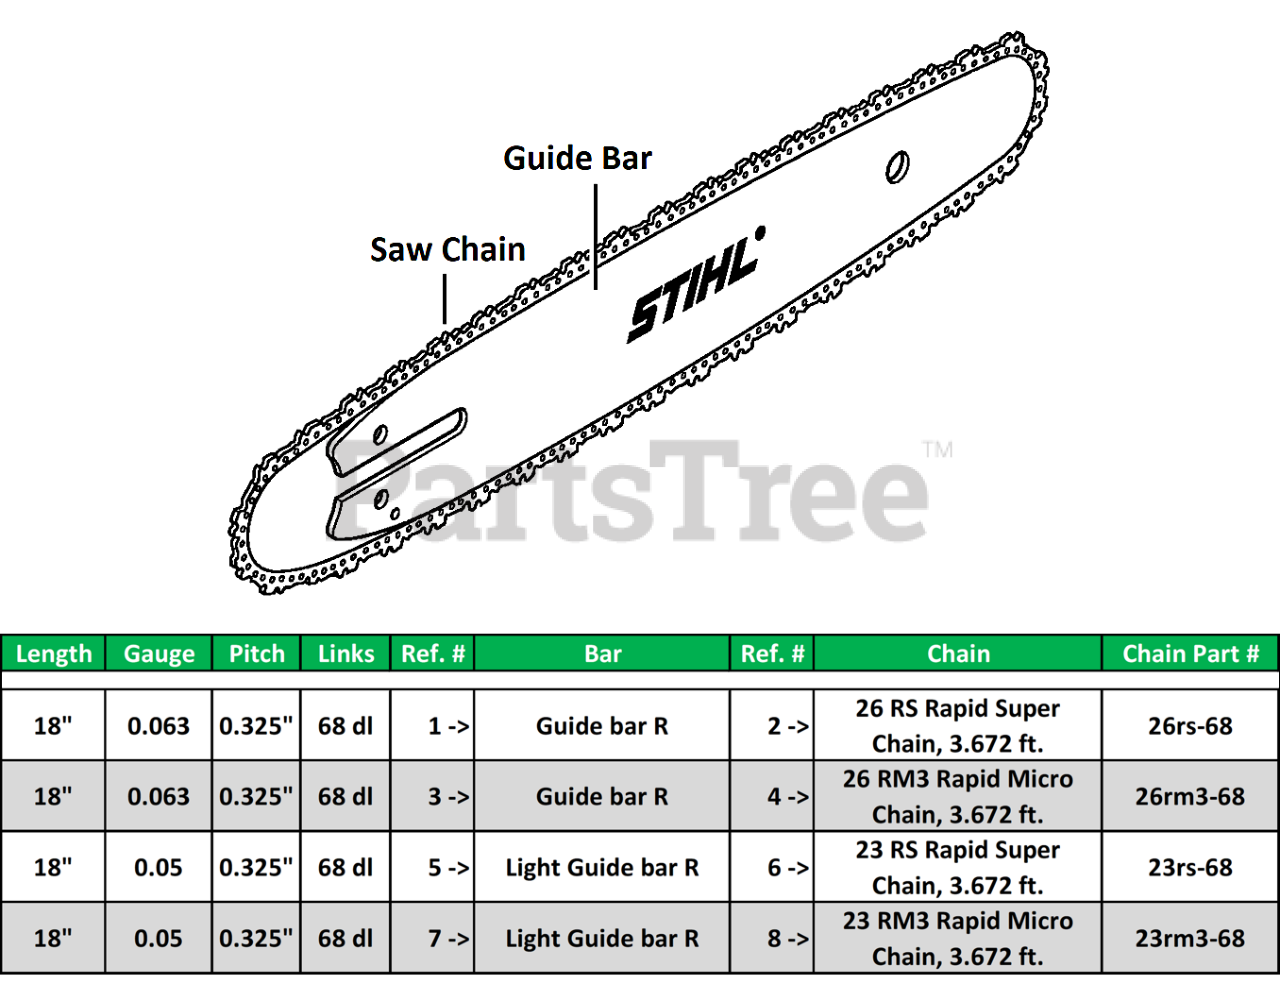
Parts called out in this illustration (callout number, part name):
1	Guide bar R 45cm/18" 1,6mm/0.063" .325"
2	26 RS Rapid Super Chain, 3.672 ft.
3	Guide bar R 45cm/18" 1,6mm/0.063" .325"
4	26 RM3 Rapid Micro Chain, 3.672 ft.
5	Guide bar R 45cm/18" 1,3mm/0.050" .325"
6	23 RS Rapid Super Chain, 3.672 ft.
7	Guide bar R 45cm/18" 1,3mm/0.050" .325"
8	23 RM3 Rapid Micro Chain, 3.672 ft.
